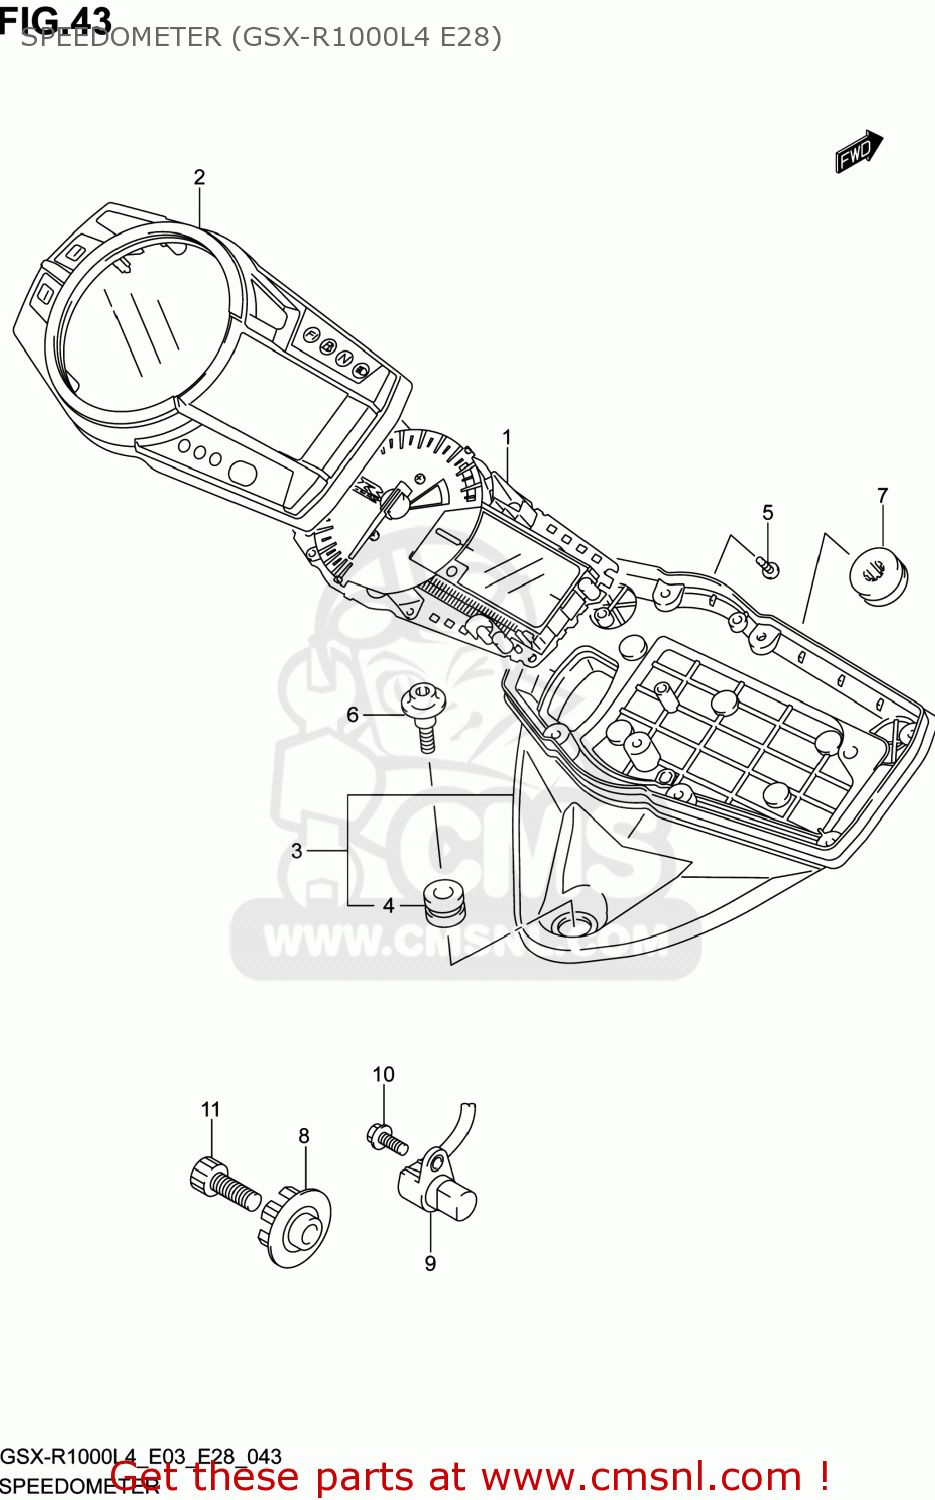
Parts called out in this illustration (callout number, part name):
1	COMBINATION METER
2	CASE ASSY,UPR
3	CASE ASSY,LWR
4	CUSHION,METER
5	SCREW(3X16)
6	SCREW,SPEEDOMETER
7	CUSHION
8	ROTOR,SPEED
9	SENSOR,SPEED
10	BOLT
11	BOLT
